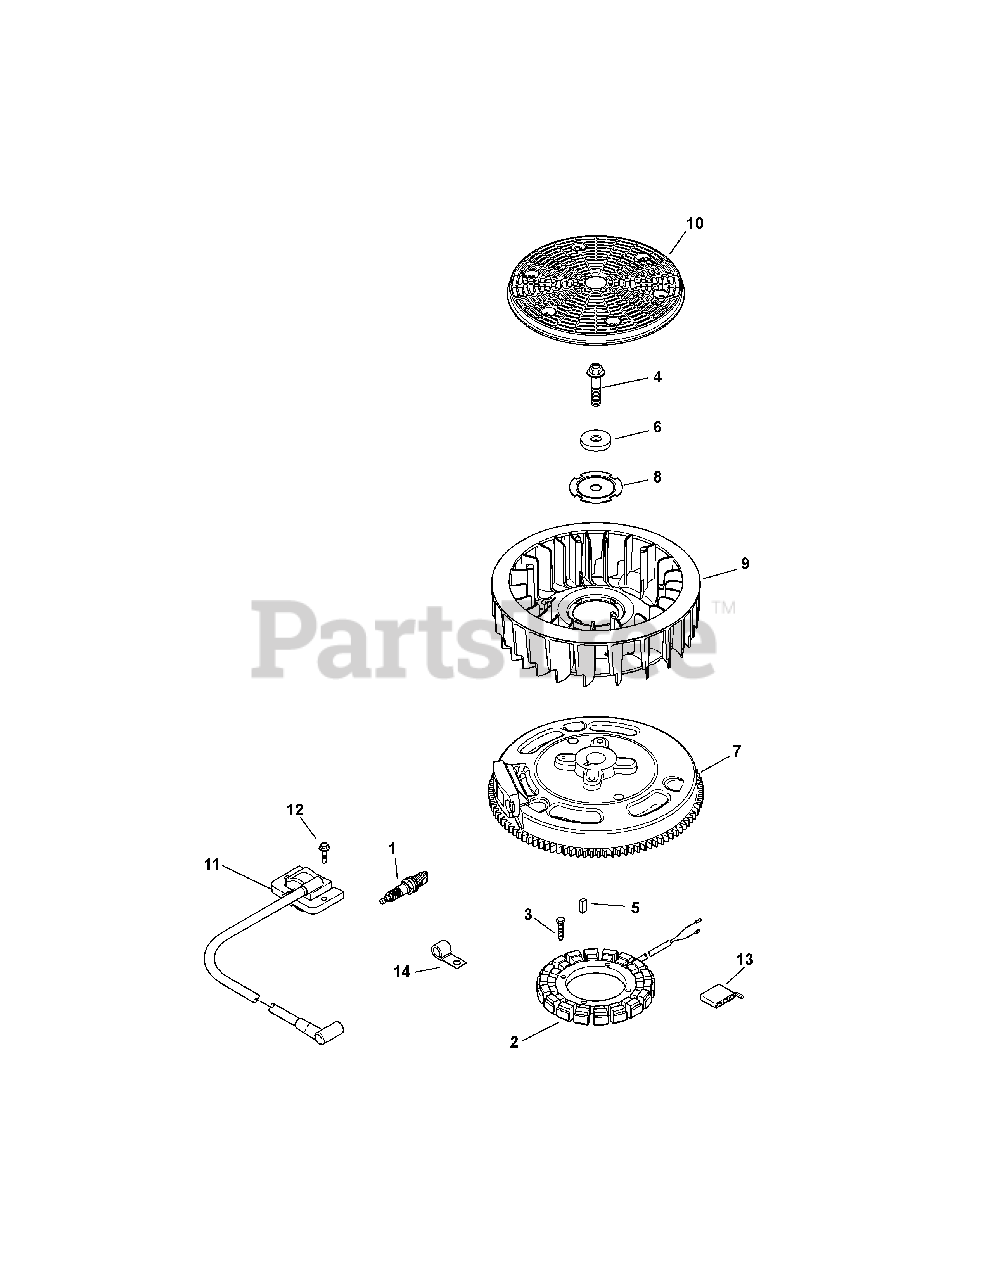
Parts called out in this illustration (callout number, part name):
1	Spark Plug
2	15 Amp Stator Kit
3	Screw, M5 x 0.8 x 25
4	Hex Flange Screw
7	Flywheel Assembly
8	Fan Mounting Plate
9	Fan
11	Ignition Module Kit
12	Flg. Thd. Frm. Screw, M5 x .8 x 20
